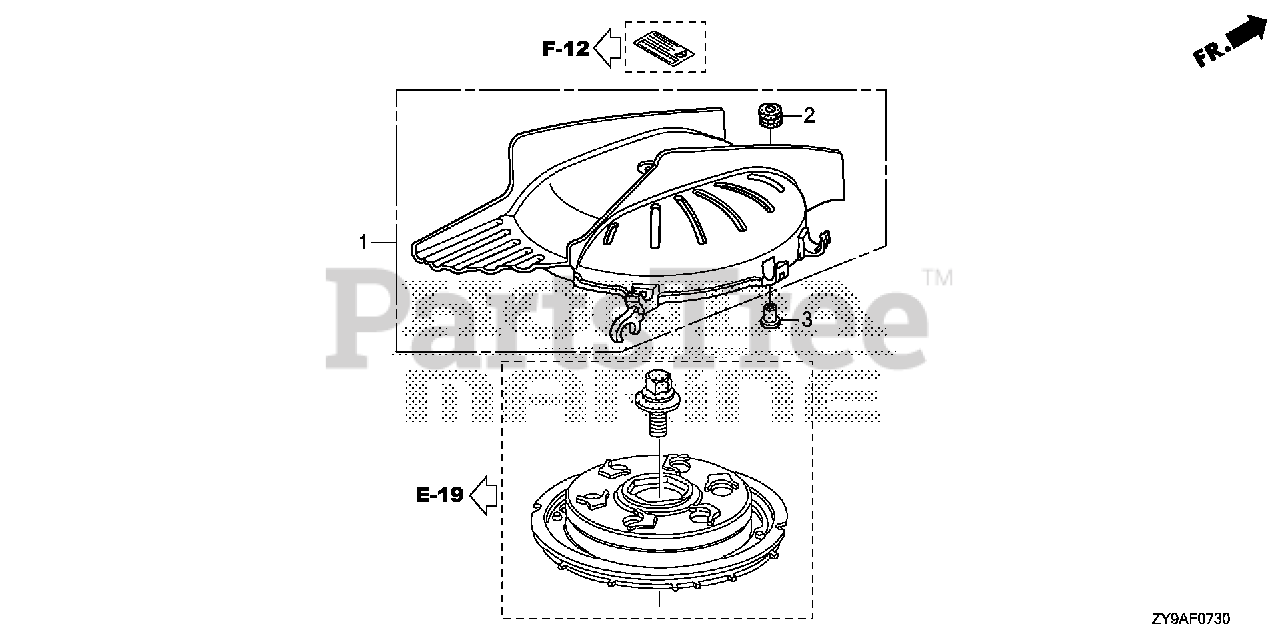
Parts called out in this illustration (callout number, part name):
1	COVER ASSY., ALTERNATOR
2	GROMMET, CASE (LOWER)
3	COLLAR, MODULE IGNITION CONTROL CASE (CDI)
